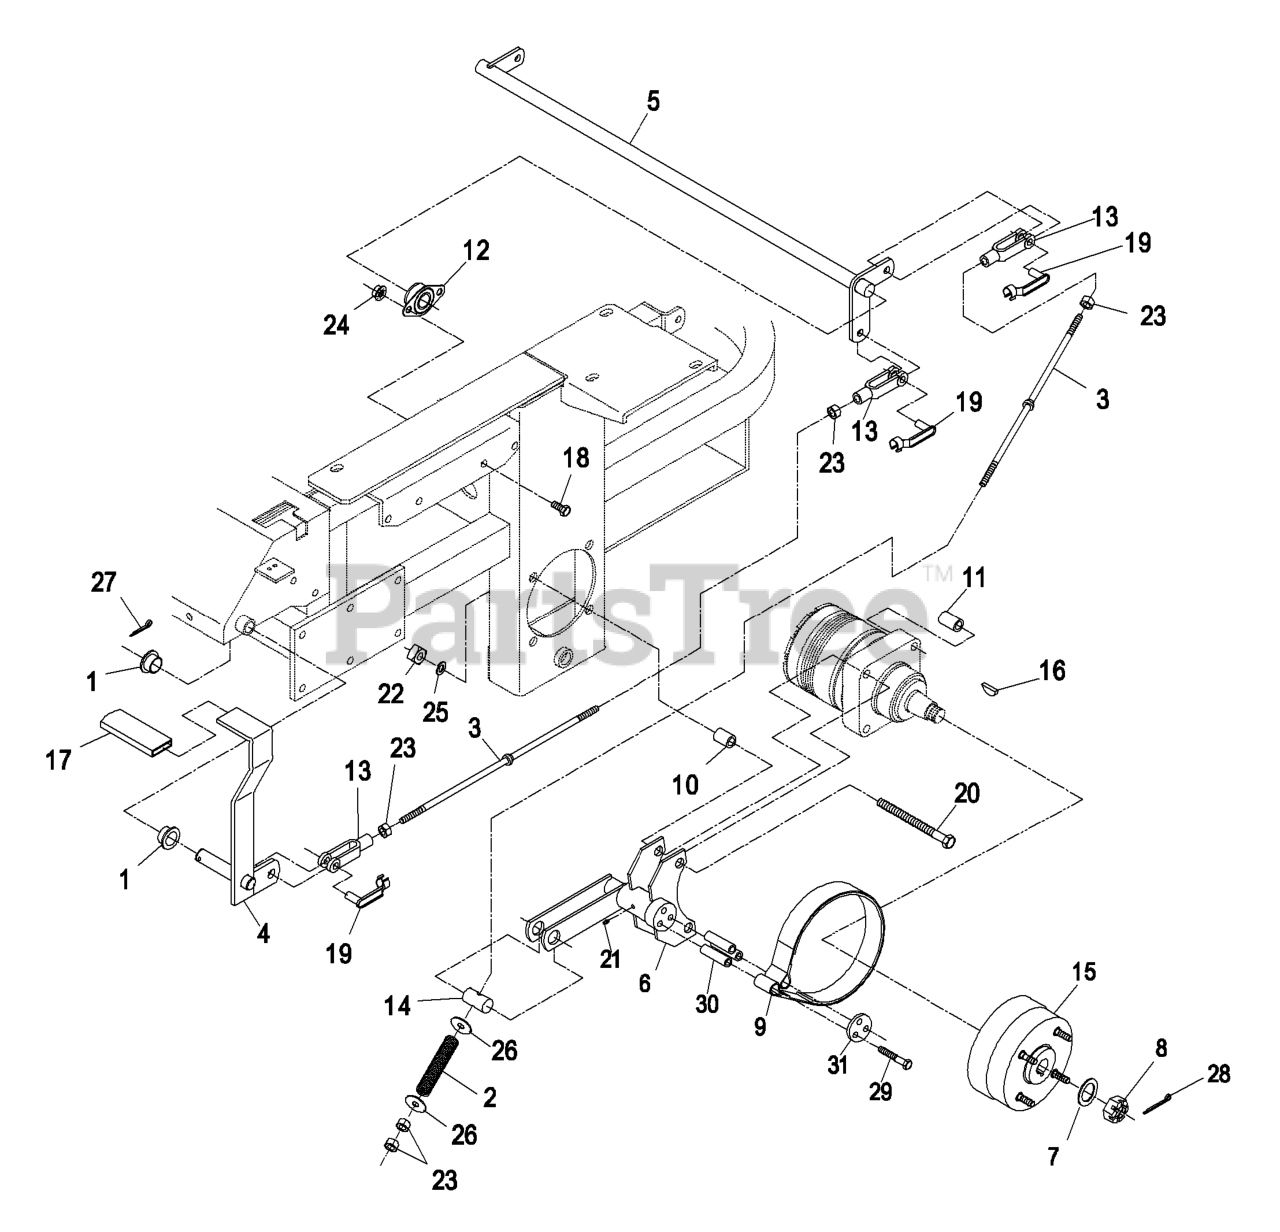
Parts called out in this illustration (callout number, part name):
1	BEARING-CONTROL
2	SPRING-BRAKE
3	ROD-BRAKE
4	BRAKE LEVER ASM
5	SHAFT-BRAKE
6	BRACKET-BRAKE
7	WASHER-SPACER
10	SPACER-WHEEL, SHORT
11	SPACER-WHEEL, LONG
12	BEARING-FLANGE, SIDE
13	YOKE-LINKAGE, BRAKE
14	PIN-TRUNION
15	WHEEL HUB ASM
16	KEY-WOODRUFF
17	GRIP-LEVER
18	SCREW-HH
19	PIN-SPRING, CLEVIS
20	SCREW-HH
21	FITTING-GREASE
23	NUT-HEX
24	NUT-HHF, WHIZ
25	WASHER-LOCK
26	WASHER-FLAT
27	PIN-COTTER
28	PIN-COTTER
29	SCREW-HH
31	RETAINER-BAND, BRAKE
